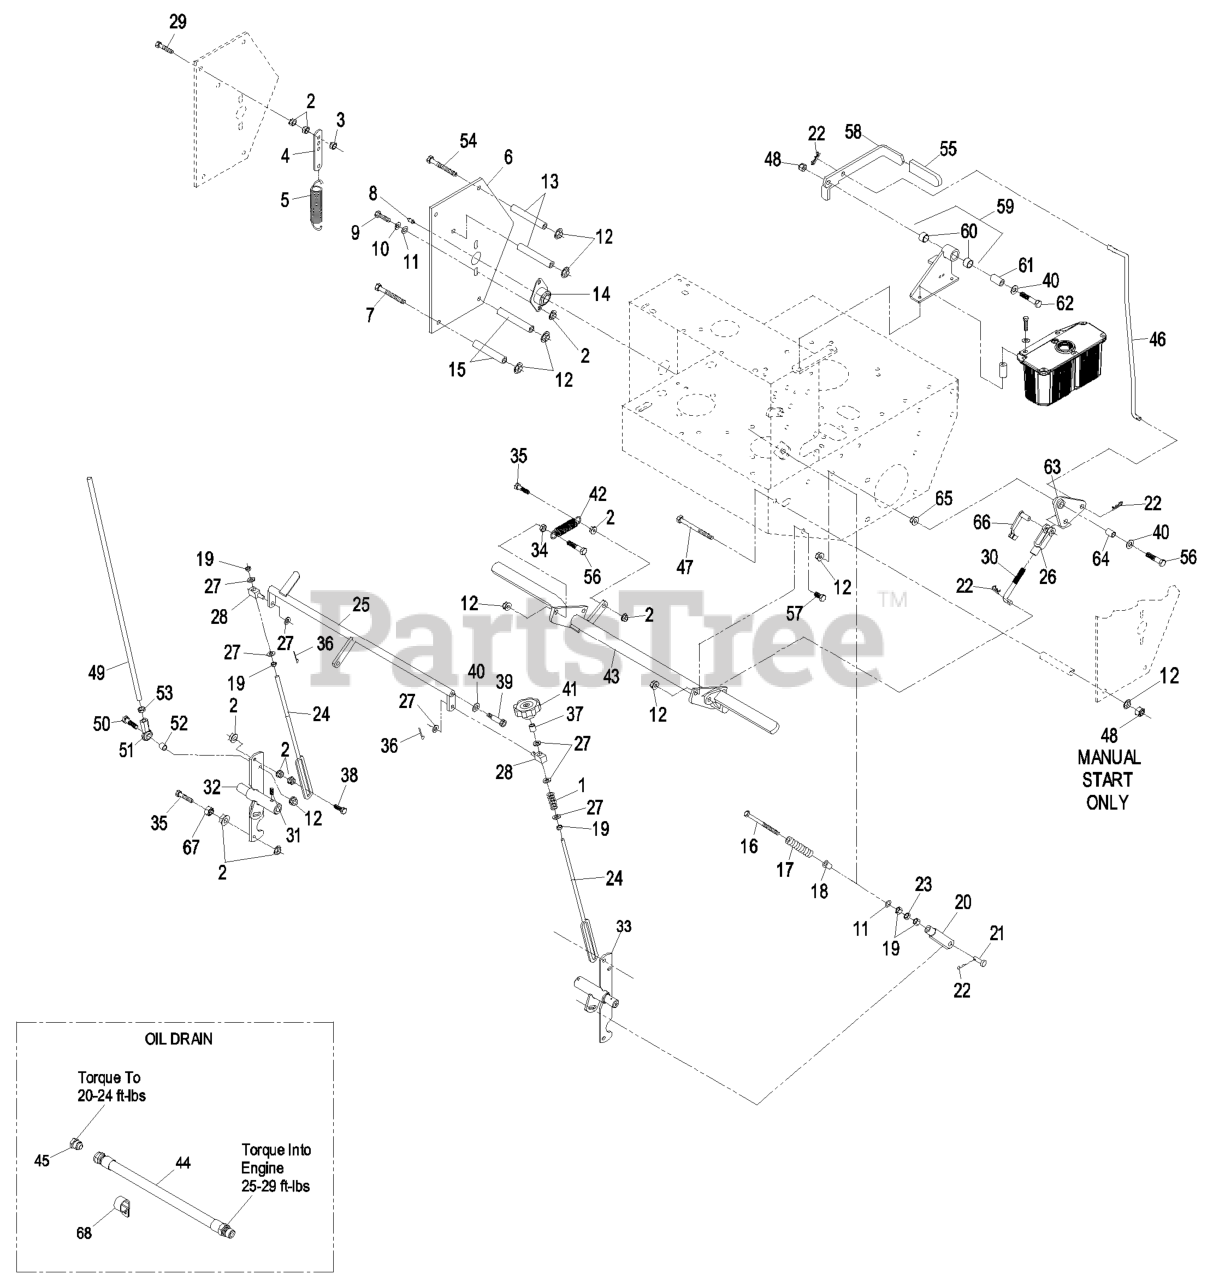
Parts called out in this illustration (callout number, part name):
1	SPRING-COMPRESSION
3	NUT-LOCK, NI
4	TAB-SPRING, EXTENSION
5	SPRING-EXTENSION
6	SHIELD-CONTROL
7	SCREW-HH
8	FITTING-GREASE
9	SCREW-HH
10	WASHER-LOCK
11	WASHER-FLAT
12	NUT-HHF, WHIZ
13	SPACER-SHIELD
14	BEARING-FLANGE, SIDE
15	SPACER-SHIELD
16	BOLT-RETURN, NEUTRAL
17	SPRING,COMPRESSION (NEUT)
18	BUSHING-FLANGED
19	NUT-HEX
20	YOKE-ADJUSTABLE
21	PIN-CLEVIS
22	PIN-COTTER
23	NUT-JAM
24	LINK-CONTROL, SPEED
25	CRANK-CONTROL, SPEED
26	YOKE-LINKAGE, BRAKE
27	WASHER-PLAIN
29	BOLT-TAP, HH
30	LINKAGE-LOWER
31	SCREW-SET
32	SHAFT-CONTROL, LH
33	SHAFT-CONTROL, RH
34	NUT-JAM
35	SCREW-HH
36	PIN-COTTER
38	SCREW-HH
39	SCREW-HSH
40	WASHER-FLAT
41	KNOB-TRACKING
42	SPRING-IDLER
46	LINKAGE,UPPER- TTHP
47	SCREW-HH
48	NUT-LOCK, NI
49	LINK,DRIVE (PLTD)
50	SCREW-HH
51	JOINT-BALL END, LH
52	SPACER-TUBE, PUMP LINK
53	NUT-HEX JAM, LH
54	SCREW-HH
55	GRIP-LEVER
56	SCREW-HH
57	SCREW-HH
58	LEVER,PARK BRK W/DECAL
59	BRACKET ASM
60	SLEEVE-BUSHING
61	BUSHING-PIVOT
62	SCREW-HH
63	BELLCRANK ASM
64	BUSHING-PLASTIC
66	PIN-SPRING, CLEVIS
67	NUT-JAM
68	CLIP-LOOM
